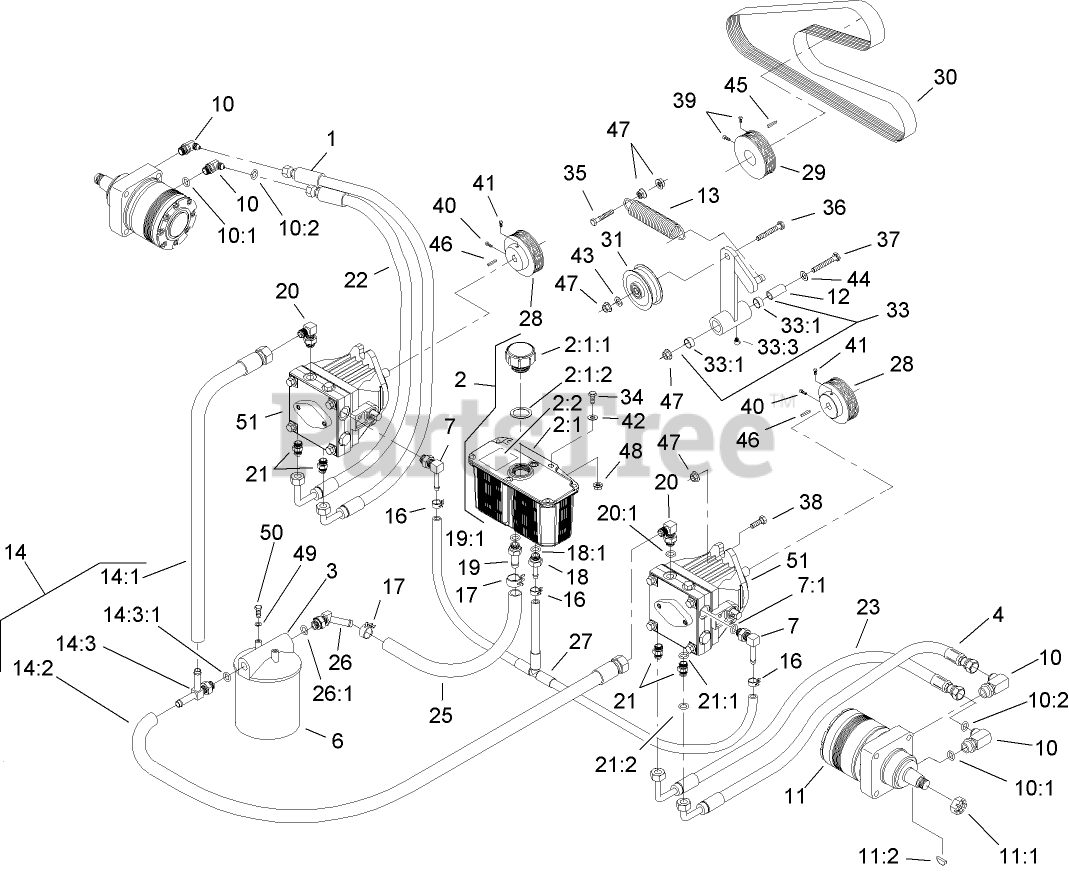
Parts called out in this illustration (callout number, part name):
1	HYD HOSE ASM
2	HYD RESERVOIR ASM
2:1	Reservoir-HYD
2:1:1	CAP-RESERVOIR, HYD
2:1:2	GASKET-CAP
2:2	DECAL-SURFACE, HOT (CE)
3	HEAD-FILTER
4	HYD HOSE ASM
6	FILTER-OIL, HYD (WINTER)
6	FILTER-OIL, HYD
7	ELBOW-90 DEG
7:1	O-RING
10	Fitting-Straight
10:1	O-RING
10:2	O-Ring
11	MOTOR-WHEEL
11:1	NUT-HH
11:2	KEY-WOODRUFF
13	Spring-Extension
14	PUMP INLET HOSE ASM
14:1	HYD Hose ASM
14:2	HYD Hose ASM
14:3	ADAPTER-RUN, TEE
14:3:1	O-RING
16	Clamp-Hose
17	Clamp-Hose
18	Adapter-Straight
18:1	O-RING
19	ADAPTER-STRAIGHT
19:1	O-RING
20	FITTING-ELBOW, 90 DEG
20:1	O-Ring
21	FITTING-STRAIGHT
21:1	O-RING
21:2	O-Ring
22	HYD HOSE ASM
23	HYD HOSE ASM
25	Hose-HYD
26	FITTING-BARBED, 45 DEG
26:1	O-RING
27	HYD Hose ASM
28	SHEAVE
29	SHEAVE
30	BELT-V
31	SHEAVE-IDLER
33	BEARING ARM ASM
33:1	SLEEVE-BEARING
33:3	FITTING-GREASE, 90 DEG
34	SCREW-HH
35	SCREW-HH
36	SCREW-HH
37	SCREW-HH
38	SCREW-HH
39	SCREW-SET
40	SCREW-SET
41	SCREW-SET
42	WASHER-FLAT
43	WASHER-FLAT
44	WASHER-FLAT
45	KEY-SQUARE
46	KEY-SQUARE
47	NUT-HHF, WHIZ
48	NUT-HF
49	WASHER-LOCK
50	SCREW-HH
51	PUMP-HYD
